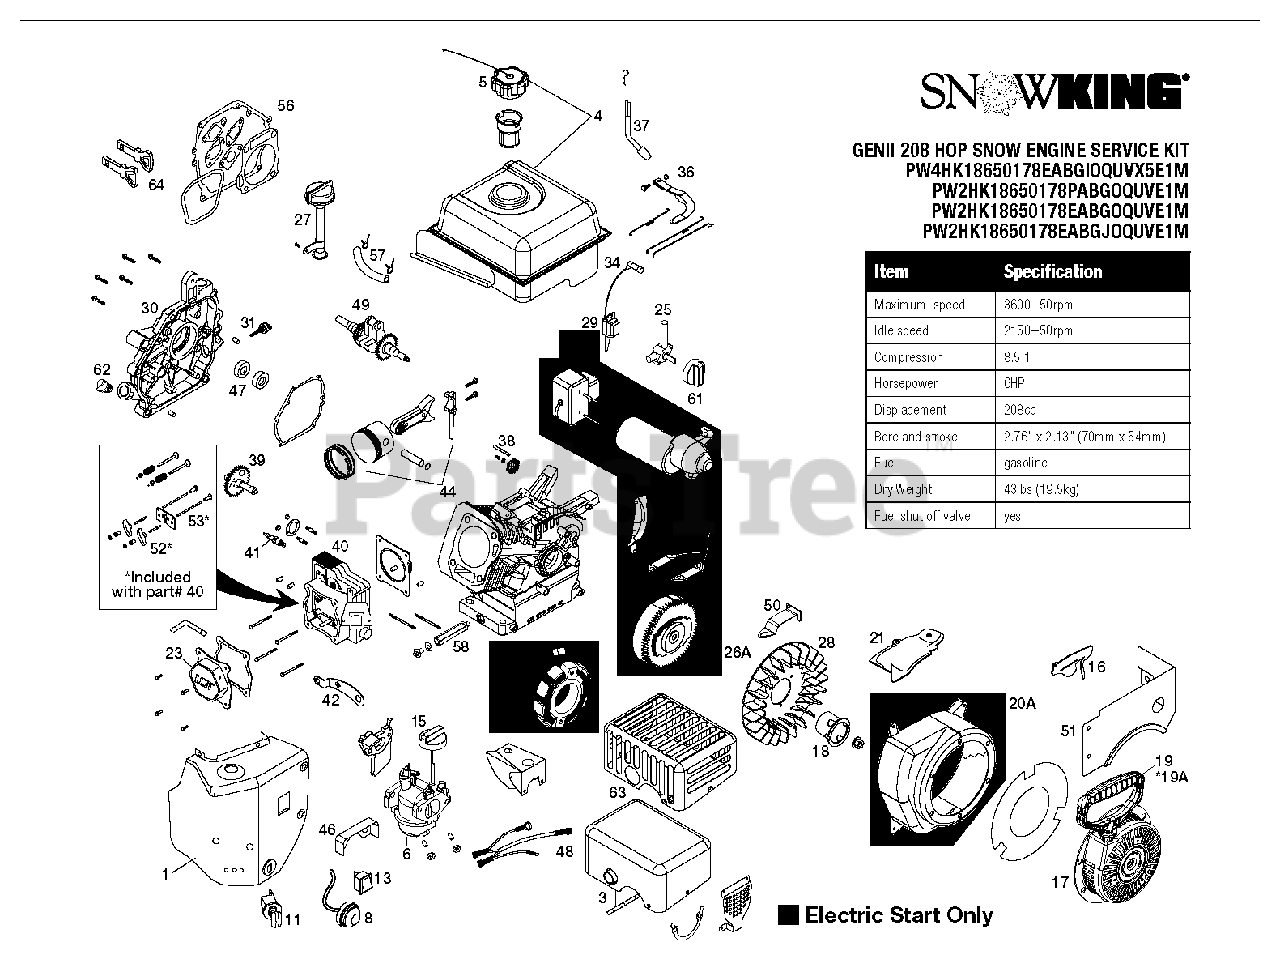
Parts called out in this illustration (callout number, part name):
1	HEATER.BOX.ASY-GEN2
3	ASSY.MUFFLER.GENII.SKSN0201.1
4	FUEL.TK.ASSY.GENII.SKSN0311.1
5	FUEL CAP OVERSIZED CLICK STYLE
6	CARB.ASSEMBLY.GEN.II.LCT.208CC
8	PRIMER.BULB.WITH HOSE (SNOW)
10	ELEC.START.GEN2.SKSN0451.1
10A	STARTER.EL.230C.SNO.LCT.208CC.
11	SWITH.KEY.ASSEM.SNOW.SINGLE.ST
13	SWITCH.ON/OFF(SKSN-0403)
15	CHOKE.KNOW.SNOW(SKSN4500)
16	GOVERNOR.LINK.SHIELD PLATE
17	RECOIL.STRT.ROUND(BLK) SNOW
18	STRTER.CUP(NON-SLOT)SKSN0601.2
19	STARTER.GRIP.SNOW.LCT.SKSN0603
20	BLOW.HSG.ASSY.ELECSKS
20A	BLOW.HSG.ASSY.ELEC(SKSN-0612)
21	SHILED.FLYWEEL.SYS(SKSN-0604)
22	SHLD.ELEC.START.FLY(SKSN-0605)
22A	SHIELD.FLYWEEL.MAN(SKSN-0607)
23	VALVE COVER ASSEMBLY
25	FUEL.PETCOCK.SNOW(SKSN4900)
26	FLYWHL.ASSY.ELECT.(SKSN0405)
26A	RP KIT.FLYWHEEL.SERVICE
26B	208CC ELEC START FLYWHEEL
27	HIGH OIL FILL DIPSTICK ASSEM
28	KIT.COOLNG.FAN.SERV(SK208-4000
29	208CC IGN COIL (STD)
29A	COIL.ING.CDI.HI TEMP.SKSNO416.
30	CRANKCASE COVER ASSY
31	DIPSTICK SMALL
32	CHARGING.COIL(ELEC)SKSN0406.1
32A	208CC 60W ALTERNATOR
34	SPARK.PLUG.BOOT.SNW,SKSN4691.1
36	KIT.GOVERNOR.ARM(SUMMER ENG)
37	KIT.GOVERNOR.CRANK(SK208-3100)
38	GOVENOR.GEARS ASM(SK2082900)
39	KIT.CAMSHAFT.208CC.LCT
40	CYLINDR.HEAD.SRV.KIT
41	SPARK.PLUG(2083810)
42	CDI.BOX.BRACKET SNOW
44	KIT.PISTON.SRV(SK208-1400)
46	SHIELD.VAPOR.SNOW
47	SEAL KIT (2 PCS)
48	WIRE.HARNESS.SNOW
49	CRANKSHAFT-KEYED(SK2081800.1)
50	SPEED.CTRL.BRKT.(SKSN0150)
51	FUEL.TNK.SKRT.GENII.SKSN0103.1
52	ROCKER ARM KIT
53	KIT.PUSH.ROD.SRV(SK208-1001)
54	CYLINDER.ASM.SKSN0001.2
56	GASKET.KIT.208CC(SK2084300.1)
57	FUEL HOSE KIT
58	EXTENDED OIL DRAIN TUBE
61	FUEL KNOB-SNOW
62	NON REMOVABLE PLUG
63	SHIELD.MUFFLER.CE.COMPLIANT
